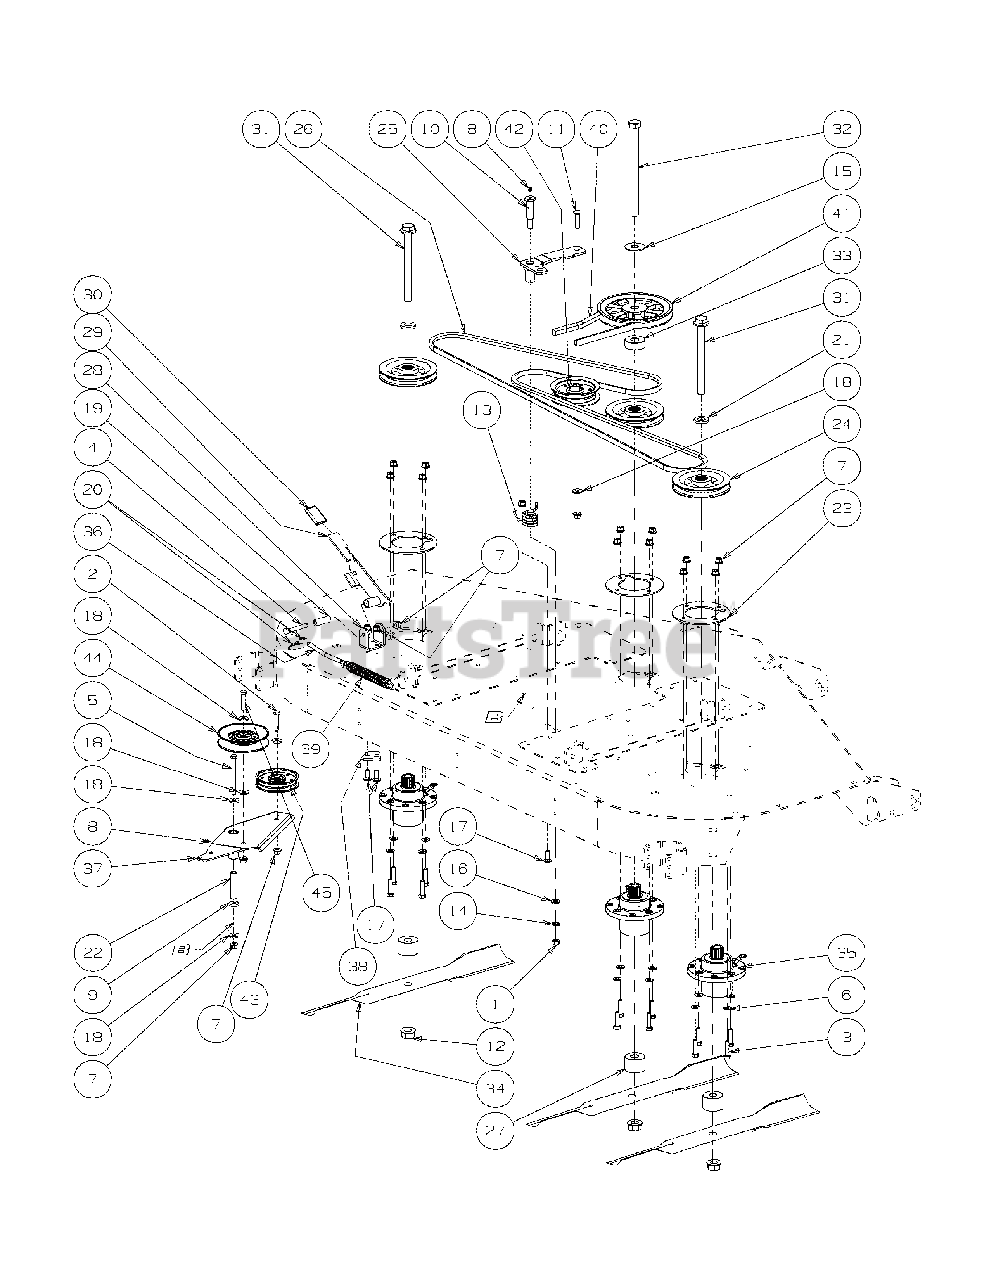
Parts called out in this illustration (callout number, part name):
1	Hex Nut, 7/16-14
2	Hex Cap Screw, 3/8-16 x 1-3/4
3	Hex Cap Screw, 3/8-16 x 1-1/2
4	Hex Cap Screw, #8-16 x 2-1/2
5	Hex Cap Screw, 3/8-16, 4.00
6	Flat Washer, 3/8
7	Flange Lock Hex Nut, 3/8-16
8	Grease Fitting, 1/4-28 x 3/16
9	Idler Washer
10	Shoulder Screw, 7/16-14
11	Hex Carriage Screw, 3/8-16, 1.75
12	Flange Hex Nut, 3/4-16
13	Torsion Idler Spring
14	Lock Washer, 7/16
15	Flat Washer, .781 ID 2.00 OD, .105
16	Flat Washer, .469 ID, .875 OD, .105
17	Carriage Bolt, 3/8-16 x 1
18	Flat Washer, .406 ID, 1.0 OD, .105
19	Spacer, .39 ID x .63 OD x 1.75
20	Cotter Pin, .072 x 1.12
21	Spacer .812 ID x .268 LG
22	Spacer, .39 ID x .625 OD x 2.75
23	Aluminum Spindle Support Plate
24	V-Pulley, 5.75 OD
25	Idler Arm Assembly includes:
25	Bearing Sleeve
26	V-Belt, B Section x 124.0 Lg
27	Spacer, .760 ID x 2.00 OD x .330
28	Tension Idler Bracket
29	Handle Tension Weldment
30	Tension Idler Handle Grip
31	Hex Cap Screw, 3/4-16, 7.50
32	Hex Cap Screw, 3/4-16, 9.50
33	Spacer, .76 ID x 2.0 OD x .790
34	Bahia Blade, 25.0, .756 ID
35	Aluminum Spindle Assembly
36	Spring Tension Rod
37	Idler Arm Assembly Service Kit
37	Bearing Sleeve in idler arm
38	Adaptor Plate
39	Extension Spring, .94 OD x 7.72
40	V-Belt, B Section x 107.0
41	V-Pulley, 7.450 OD x .750 Bore, Cast
42	Idler Pulley, 4.06 OD
43	PULLEY-FLAT IDLER 4.875
44	Idler Pulley, 5.06 Dia.
45	Hex Cap Screw, 3/8-16 x 2.00
